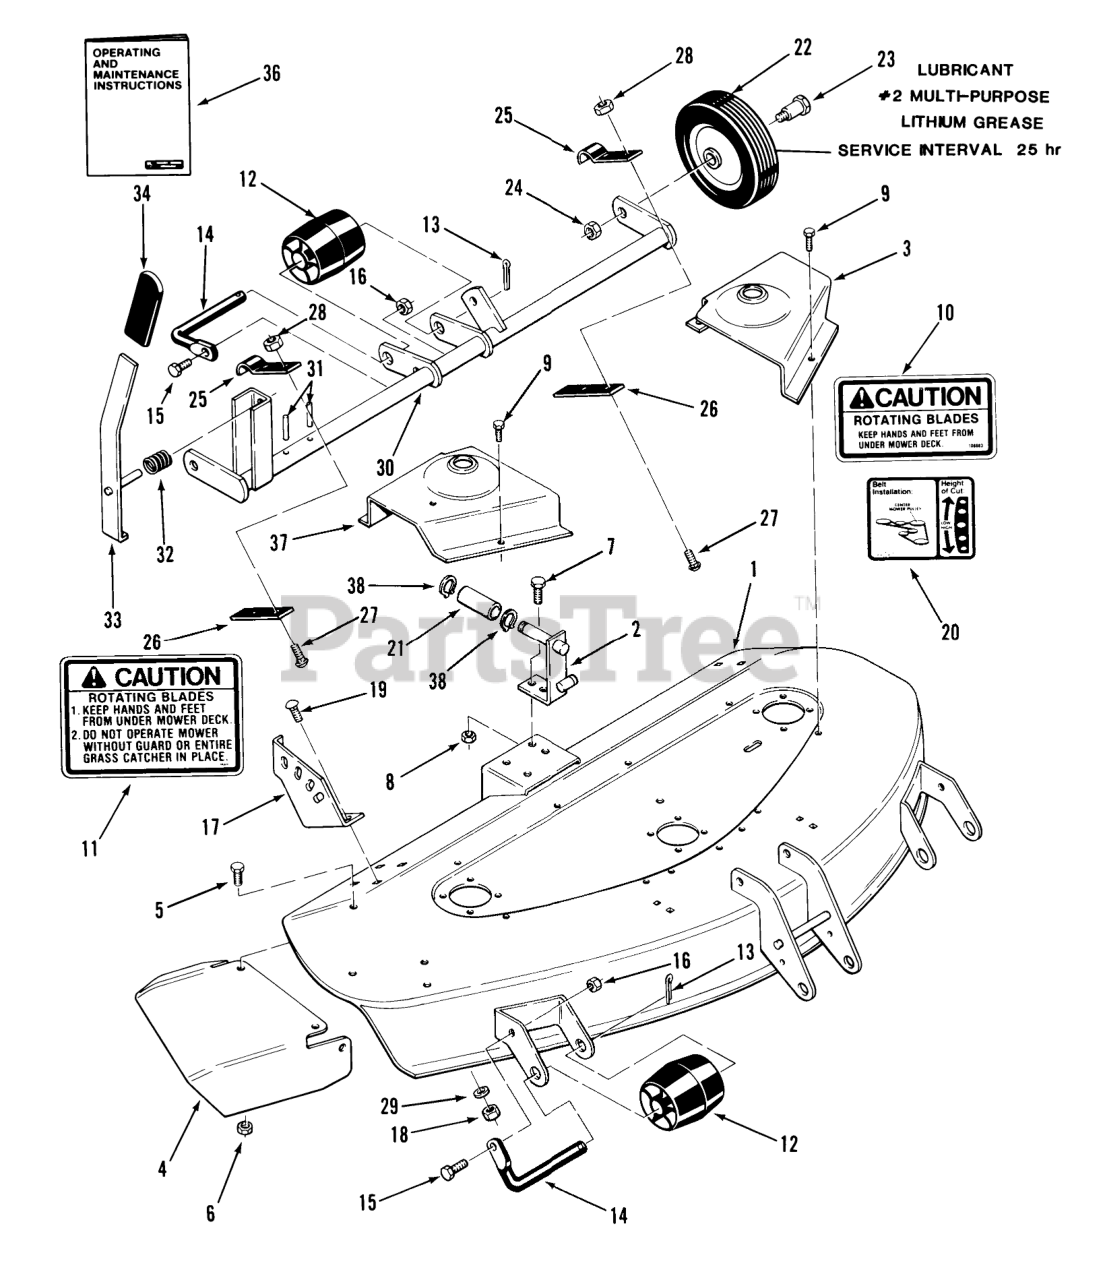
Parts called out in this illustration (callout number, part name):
1	ASSY 42" SIDE MOW R
2	ASSY BRACKET GUID R
3	COVER-BELT LH R
4	Chute Extension
5	Bolt
6	Nut
7	BOLT
8	Nut
9	SCREW -4
10	Caution Decal
11	DECAL
12	Roller
13	Cotter Pin
14	ROLLER-SHAFT
15	H H C S
16	Nut
17	Quadrant
18	Nut
19	Bolt-Carriage
20	DECAL-HEIGHT BELT
21	SPACER
22	WHEEL
23	BOLT-SHOULDER
24	Nut
25	Clamp
26	Bar
27	Bolt
28	NUT
29	Washer
30	Gage Wheel Support
31	PIN-SPIROL
32	SPRING-COMPRESSION
33	LEVER ASSY R
36	Operating & Maintenance Instructions
37	COVER-BELT RH R
38	Snap Ring
